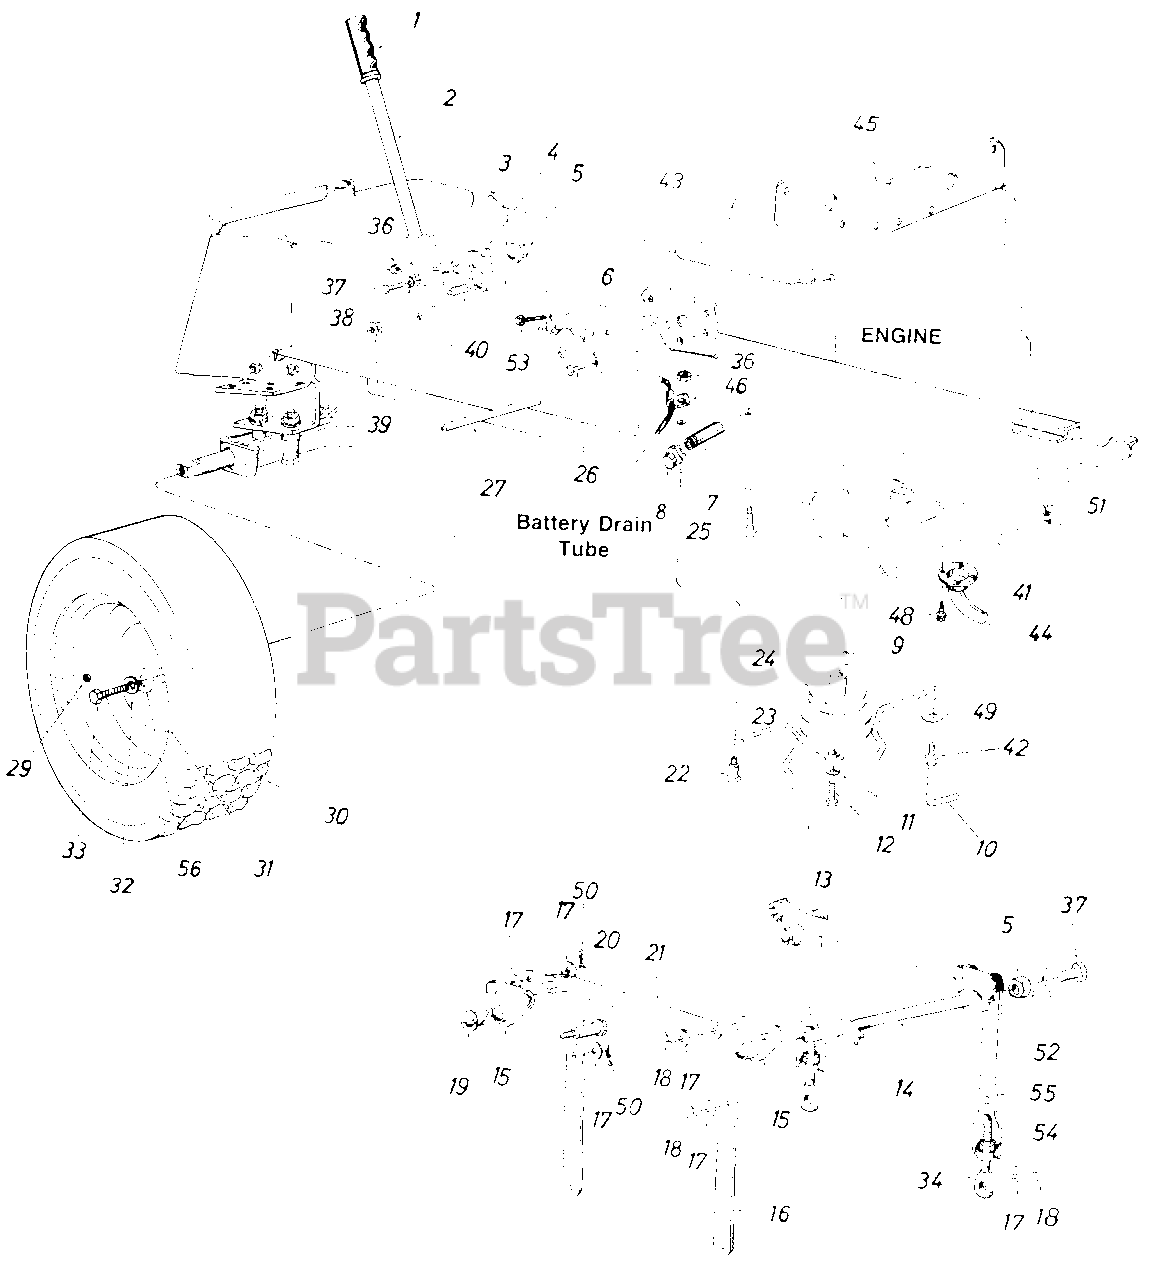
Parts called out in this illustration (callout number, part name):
1	Grip
2	Lift Handle Ass'y.
3	Hex Scr. 5/16-18 x 1.50" Lg.
4	Lift Shaft Drive
5	Plastic Hex Brg. 518" I.D.
8	Pipe Cap 3/8-18 Npt.
9	Sq. Key 114" x 1.50" Lg.
10	Belt Guard Lock Pin
11	L-Wash. 7/16" Scr
12	Hex Scr. 7/16-20 x 1.50" Lg.
13	Belt Guard
14	Lift Shaft Ass'y.
15	Lift Pivot Brkt. Ass'y.
17	Fl-Wash. 1/2" I.D. x 1.00" O.D. x .090
18	Hairpin Cotter
19	Nyliner 5/8" I.D. x .88" Lg.
20	Shld. Scr. 5/8" Dia. x .96" Lg. 3/8-16
23	Flat Wash. .44" I.D. x 1.25" O.D. x .17
24	Two-Step Engine Pulley
25	Hex Wash. Hd. Scr. 3/8-16 x 1.25" Lg.
26	Hex Thd. Rolling Scr. 5/16-24 x .50" Lg.
27	Running Board Rod
29	Air Valve
30	Rear Wheel Ass'y. Comp.
31	Rear Wheel Rim Only
32	Bell-Wash. .345" I.D. x .88" O.D.
33	Hex Bolt 5/16-24 x .75" Lg.
34	Eye Bolt Adj. Link 1/2-13 Thd.
36	Hex Cent. L-Nut 5/16-18 Thd.
37	Hex Scr. 5/16-24 x .62" Lg.
38	L-Wash. 5/16" I.D.
39	Hex Center L-Jam Nut 3/8-16 Thd.
40	Compression Spring
41	Deck Connecting Rod
42	Hex Nut 5/16-24 Thd.
45	Heat Shield
46	Mounting Clamp
48	Hex Wash. Hd. AB-Tap Scr. #10 x .50" Lg.
49	Bell-Wash..39" I.D.
50	Cotter Pin .09 Dia. x 1.0" Lg.
51	Int. Cotter Pin
52	Flat Wash. .34" I.D. x 1.12" O.D. x .125
53	Hex Wash. Hd. AB-Tap Scr. 5/16 x .62" Lg.
54	Hex Nut 1/2-13 Thd.
55	Adj. Deck Link
56	Fl-Wash. .34" I.D. x 2.0" O.D.
